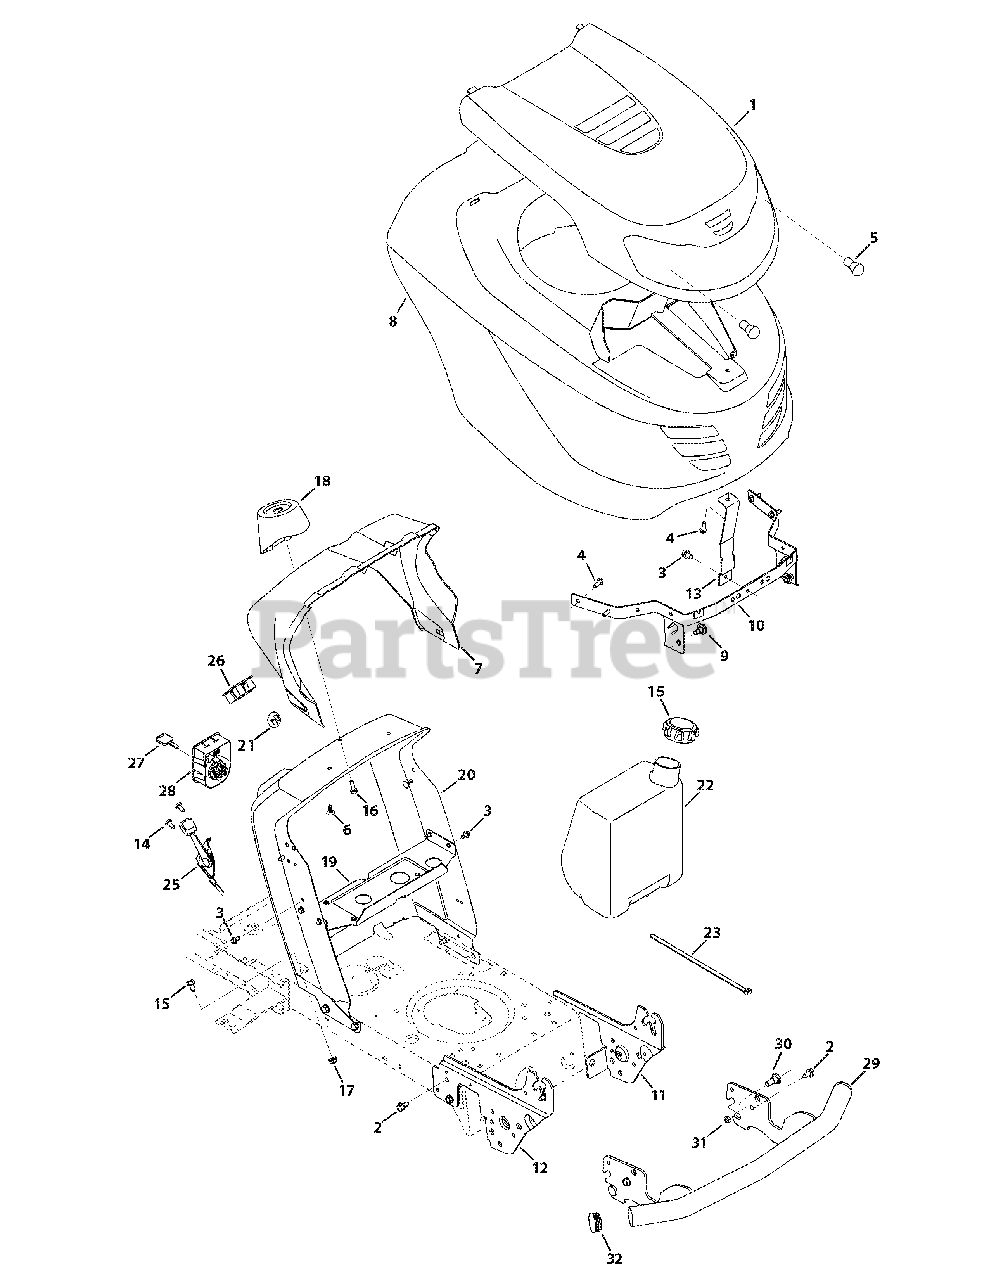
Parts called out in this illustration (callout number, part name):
1	Hood Style G
2	S-Tapp Scr 5/16-18 x .75
3	Hex Wash S-Tapp Scr 1/4-20 x .50
4	Hex Tapp Scr 1/4 x .75" Lg.
5	Miniature Lamp 12V Socket Type
6	Rachet Clip
7	Dash Collar
8	Hood Style G
9	Shoulder Screw 5/16-18, .43 x .29
10	Pivot Hood Bracket
11	LH Pivot Bracket
12	RH Pivot Bracket
13	Hood Support Bracket
14	Hex Wash Hd Scr. 1/4-20 x .500
15	Cap-Fuel
16	Hex Tapp Scr 1/4 x .75" Lg.
17	Flange Locknut 5/16-18 Gr. F, Nylon
18	Steering Support
19	Gas Tank Support Bracket
20	Dash Assembly
21	Choke Plug
22	Fuel Tank 1.5 gal.
23	Cable Tie
25	Choke/Throttle Cable
26	Indicator Monitor
28	Key Switch Module
29	Bumper Ass'y
30	Shoulder Scr. .498 x .340: 3/8-16
31	Hex L-Nut 3/8-16 Gr. B
